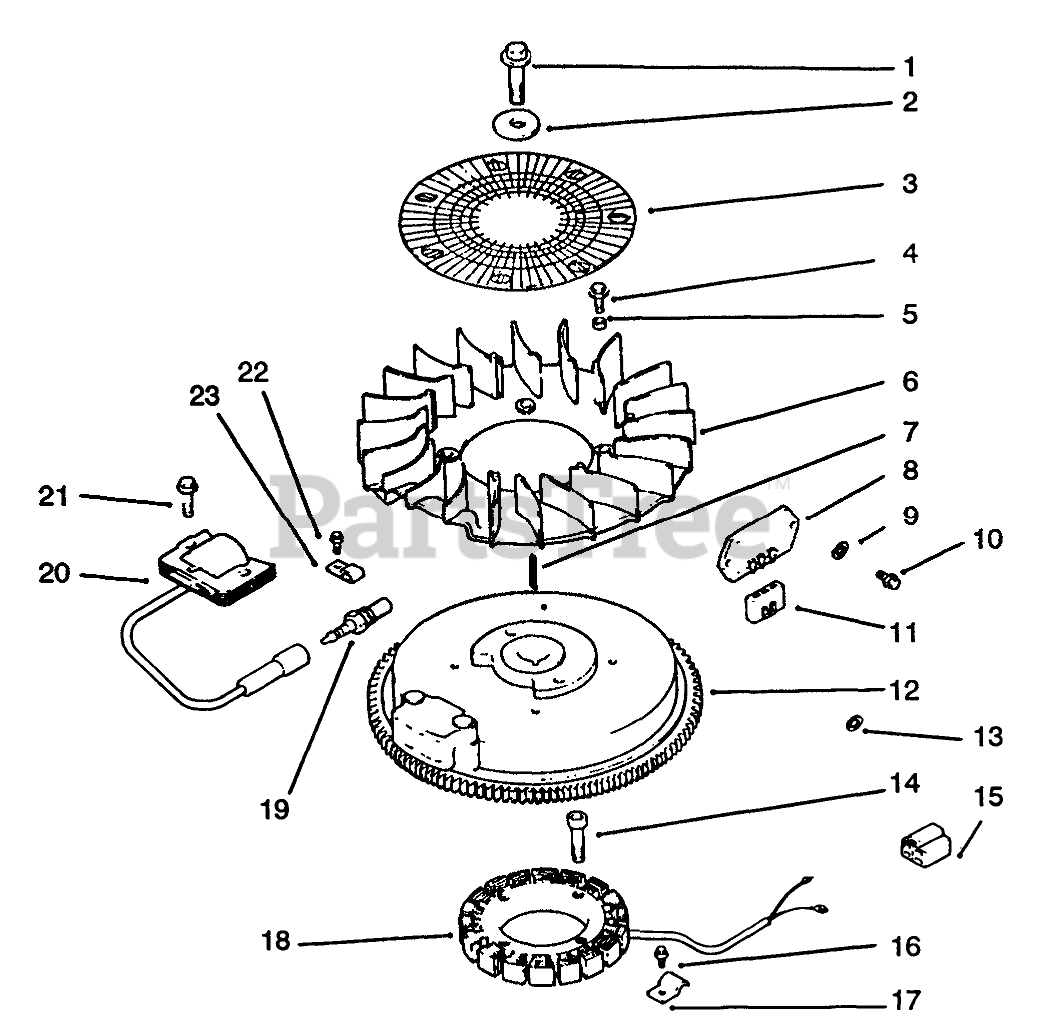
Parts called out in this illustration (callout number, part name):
1	Screw-Flywheel Mounting (Only On: 72042, 72063, 72062, 72043)
2	Washer-Flywheel Screw (Only On: 72042, 72063, 72062, 72043)
3	Screen-Grass (Only On: 72042, 72063, 72062, 72043)
4	Screw M6x1.0x16 (Only On: 72042, 72063, 72062, 72043)
5	Spacer-Fan (Only On: 72042, 72063, 72062, 72043)
6	Fan (Only On: 72042, 72063, 72062, 72043)
7	Key (Only On: 72042, 72063, 72062, 72043)
8	Rectifier-Regulator (Only On: 72042, 72063, 72062, 72043)
9	Washer-Lock (Only On: 72042, 72063, 72062, 72043)
10	Screw M6x1.0x16 (Only On: 72042, 72063, 72062, 72043)
11	Connector-Regulator (Only On: 72042, 72063, 72062, 72043)
12	Flywheel ASM (Only On: 72042, 72063, 72062, 72043)
13	Washer-Flat (Only On: 72042, 72063, 72062, 72043)
14	Screw M5x0.8x25 (Only On: 72042, 72063, 72062, 72043)
15	Connector-5 Contact (Only On: 72042, 72063, 72062, 72043)
16	Screw M5x0.8x10 (Only On: 72042, 72063, 72062, 72043)
17	Clip-Stator Harness (Only On: 72042, 72063, 72062, 72043)
18	Stator-15 Amp (Only On: 72042, 72063, 72062, 72043)
19	Spark Plug (Only On: 72042, 72063, 72062, 72043)
20	Module-Ignition (Only On: 72042, 72063, 72062, 72043)
21	Screw M5x0.8x20 (Only On: 72042, 72063, 72062, 72043)
22	Screw M5x0.8x10 (Only On: 72042, 72063, 72062, 72043)
23	Clip-Kill Lead (Only On: 72042, 72063, 72062, 72043)
